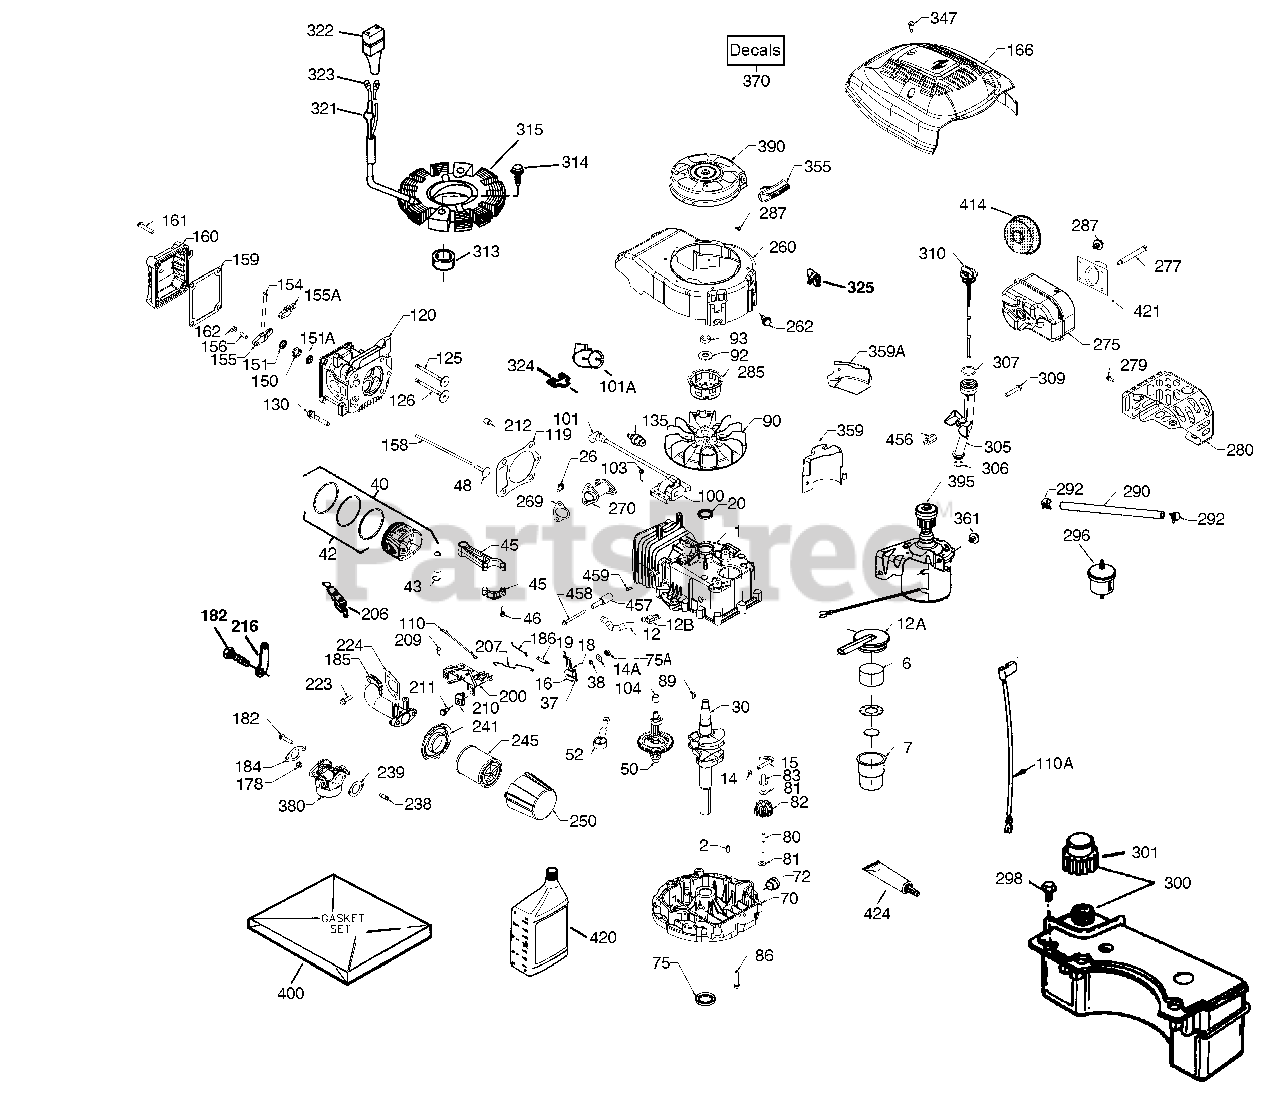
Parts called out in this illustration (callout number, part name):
1	"Order Engine or Short Block
2	Dowel Pin
6	Breather Element
7	Breather Ass'y. (Incl. 6 & 12A)
12	Breather Tube
12A	Breather Cover & Tube (Incl. 12B)
12B	Breather Tube Elbow
14	Washer, 5/8 x 17/64 x 1/64"
15	Governor Rod (Incl. 14)
16	Governor Lever
18	Screw, T-25, 10-32 x 63/64"
19	Extension Spring
20	Oil Seal
26	Screw, 1/4-20 x 19/32"
30	Crankshaft 43)
37	Square Nut
38	Retaining Ring
40	Piston, Pin & Ring Set (Std.)
40	Piston, Pin & Ring Set (.010" OS)
42	Ring Set (Std.)
42	Ring Set (.010" OS)
43	Piston Pin Retaining Ring
45	Connecting Rod Ass'y. (Incl. 46)
46	Connecting Rod Bolt
48	Valve Lifter
50	Camshaft (Exhaust MCR)
52	Oil Pump Ass'y.
70	Mounting Flange (Incl. 72, 75 & 80)
72	Oil Drain Plug (Flush Mount)
75	Oil Seal
75A	Oil Seal
80	Governor Shaft
81	Washer
82	Governor Gear Ass'y. (Incl. 81)
83	Governor Spool
86	Screw, 1/4-20 x 1-5/16"
89	Flywheel Key
90	Flywheel (w/ring gear)
92	Belleville Washer
93	Flywheel Nut
100	Solid State Ignition
101	Spark Plug Cover
101A	Spark Plug Shield
103	Screw, T-15, 10-24 x 15/16"
110A	Ground Wire - Black, 7-3/4''
110A	Ground Wire (green) 11-3/4"
119	* Cylinder Head Gasket
120	Cylinder Head
125	Exhaust Valve (Std.) (Incl. 151)
126	Intake Valve (Std.) (Incl. 151)
130	Screw, 5/16-18 x 1-7/8"
135	Resistor Spark Plug (RN4C) also avail able in Packaged Part #740069
150	Valve Spring
151	Valve Spring Cap
151A	Valve Seal
154	Rocker Arm Pivot Pin Ass'y.
155	Rocker Arm
155A	Rocker Arm Exhaust
156	Rocker Arm Stud, 1/4-28 x 3/4"
158	Push Rod
159	* Rocker Arm Cover Gasket
160	Rocker Arm Cover
161	Screw, 1/4-20 x 1-3/8"
162	Nut, 1/4-28
178	Nut & Lock Washer 1/4-28
182	Screw, 1/4-28 x 1-1/8"
184	* Carburetor Gasket
185	Intake Pipe
186	Governor Link
200	Control Bracket
207	Throttle Link
209	Scerw, 12-16 x 5/8"
210	Conduit Clip
211	Screw, 10-32 x 3/8"
212	Bushing
223	Screw, 1/4-20 x 7/8"
224	* Intake Pipe Gasket
238	Screw, 10-32 x 49/64"
239	* Air Cleaner Gasket
241	Air Filter Collar (Black)
245	Air Filter (Paper) (also available in Packaged Part #740091) also availabl e in Packaged Part #740091
250	Air Filter Cover
260	Blower Housing
262	Screw, 1/4-20 x 1/2"
269	* Exhaust Manifold Gasket
270	Exhaust Manifold
275	Muffler (Incl. 277)
277	Screw, 1/4-20 x 2-39/64"
285	Starter Cup
287	Screw, 8-32 x 21/64"
290	Fuel Line (8.62")
292	Fuel Line Clamp
296	Fuel Filter (Incl. 292) also availabl e in Packaged Part #740093
305	Oil Fill Tube
306	* "O" Ring
307	"O'' Ring
309	Screw, 1/4-20 x 1-3/8"
310	Dipstick
314	Screw, 1/4-20 x 3/4"
315	Alternator Coil (1.5)(Incl. 321-323)
322	Connector Body
323	Terminal
355	Starter Handle
359	Starter Guard
370	Decal - Tecumseh Logo for Top of Reco il Starter
380	Carburetor (Incl. 184)
390	Rewind Starter
395	12V Electric Starter Motor Has welded washer on mtg. bracket for use on no n-flywheel brake applications.
400	Gasket Set n notes)
414	Spark Arrestor Screen
420	SAE 30 4-Cycle Engine Oil (Quart)
421	Exhaust Adapter Tube
424	Adhesive Seal
456	Oil Fill Tube Spacer
457	Shoulder Spacer
458	Screw, 10-24 x 2-3/8"
999	Summer Maintenance Kit includes 20 oz . - SAE30 Oil, spark plug, air filter , fuel stabilizer
